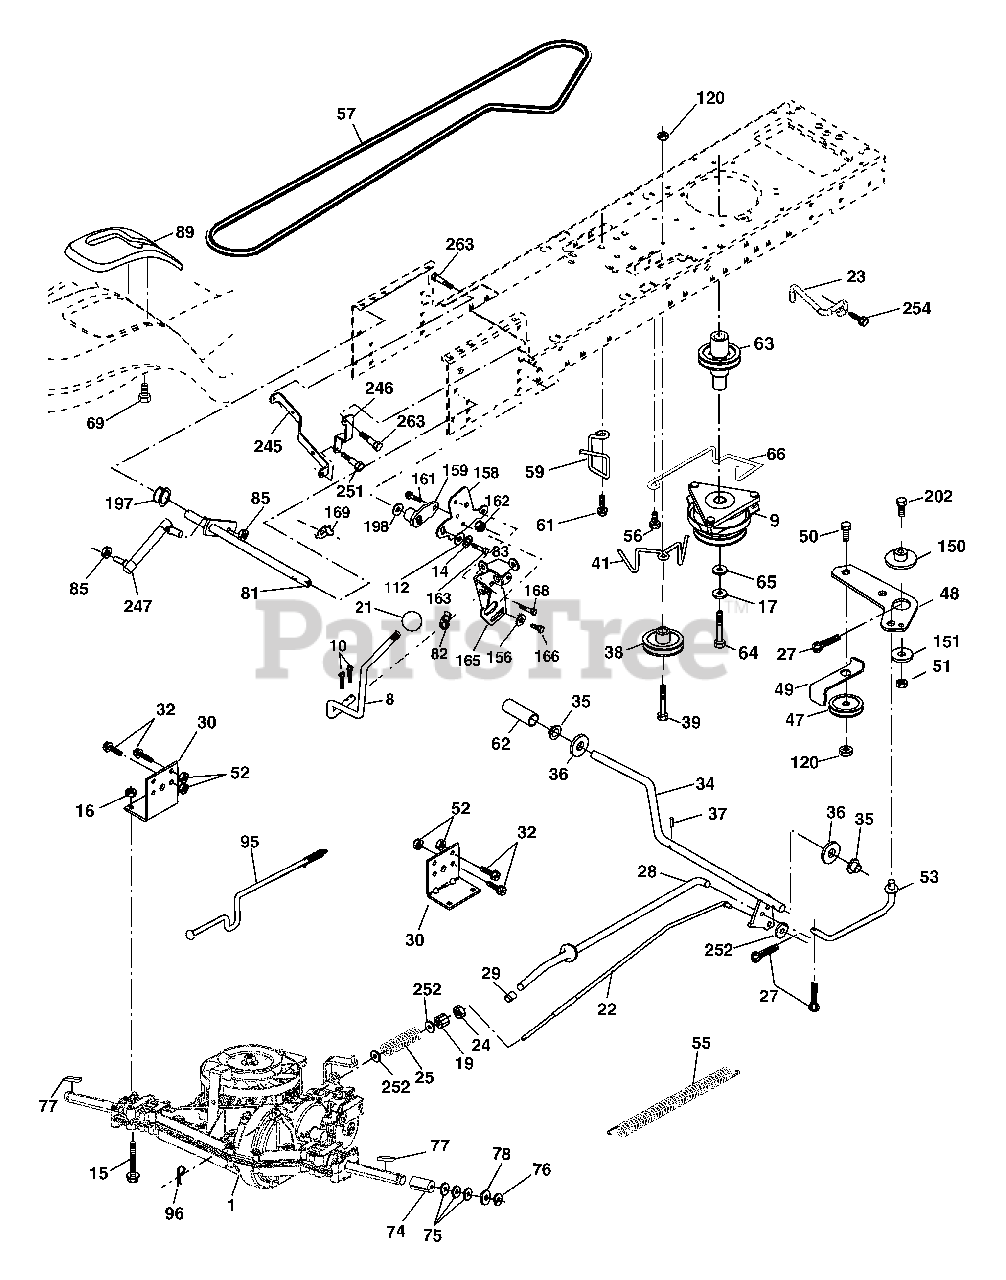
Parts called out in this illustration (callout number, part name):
8	Rod Shift Fender Adjust
9	Clutch Ogura
10	Pin Cotter 1/8 x 1 CAD
14	Washer Lock Hvy Helical
15	Bolt Hex FLGHD 5/16-18 Gr.5
16	Nut Lock Hex W/Ins. 5/16-18 unc
17	Washer 1-1/2 OD x 15/32 ID x .250
19	Nut Lock Hex W/Wsh 3/8-16 unc
21	Knob 1/2-13
22	Rod, Brake
23	Bracket Anti-Rotation
24	Nut, Hex Jam 3/8-16 unc
25	Spring, Brake Rod
27	Pin Cotter 1/8 x 3/4 CAD.
28	Rod, Parking Brake
29	Cap, Parking Brake
30	Bracket, Transaxle
32	Bolt Hex Hd 5/16-18 unc x 3/4
34	Shaft, Foot Pedal
35	Bearing, Nylon
37	Pin, Roll
38	Pulley, Composite
39	Bolt RDHD 3/8-16 unc x 2 3/4 Gr. 5
41	Keeper, Belt Idler
47	Pulley, Idler, V-Groove
48	Bellcrank, Clutch
49	Retainer, Belt
50	Bolt Carr Sh 3/8-16 x 1-1/2 Gr 5
51	Nut Crownlock 3/8-16 unc
52	Nut, Crownlock 5/16-18 unc
53	Link, Clutch
55	Spring, Return, Clutch
56	Screw 3/8-16 x 1-1/4
59	Keeper, Center Span
61	Screw 3/8-16 x .875
62	Cover, Pedal
63	Pulley, Engine
64	Bolt Hex 7/16-20 x 4 Gr. 5
65	Washer
66	Keeper Belt Engine Hydro
69	Screw Hex Wsh Hi-Lo 1/4-1/2 unc
75	Washer 25/32 x 1-1/4 x 16 Ga.
77	Key, Square
78	Washer 25/32 x 1-5/8 x 16 Ga.
81	Shaft Asm Cross Tapered
82	Spring Torsion
83	Washer 17/32 x 3/4 x 16 Ga.
85	Nut Lock Center 1/4-28 FNTHD
89	Console, Shift
95	Disconnect Asm Rod Bypas LTH
96	Retainer Spring 1" Zinc/Cad
112	Washer 9/32 x 3/4 x 10 Ga.
120	Nut Lock Flg 3/8-16
150	Spacer Retainer
151	Washer 13/32 x 2 x 10 Ga.
156	Washer Srrted 5/16 ID x 1.125
158	Bracket Shift Mount
159	Hub Shift
161	Bolt Rdhd Sqnk 1/4-20 x 3/4 Gr 5
162	Nut Crownlock 1/4-20 unc
163	Bolt Hex Fin 1/4-20 unc x 1 Gr 5
165	Bracket Pivot Lever
166	Screw 5/16-18 x 5/8
168	Bolt Shoulder 5/16-18 x .561
169	Plate Fastening
197	Nyliner Snap-In 5/8" ID
198	Washer Nyl 7/8 ID x .105" Hyd
202	Bolt Carr Sh 3/8-16 x 1-3/4 Gr.5
245	Strap Torque Lh LTH2000
246	Strap Torque Rh LTH2000
247	Link Shift Transaxle LTH2000
251	Screw 5/16-18 x 1
252	Washer 13/32 x 1 x 16 Ga.
254	Screw 3/8-16 x 1
263	Screw Hex Wsh Thdr 3/8-16 x 3/4
